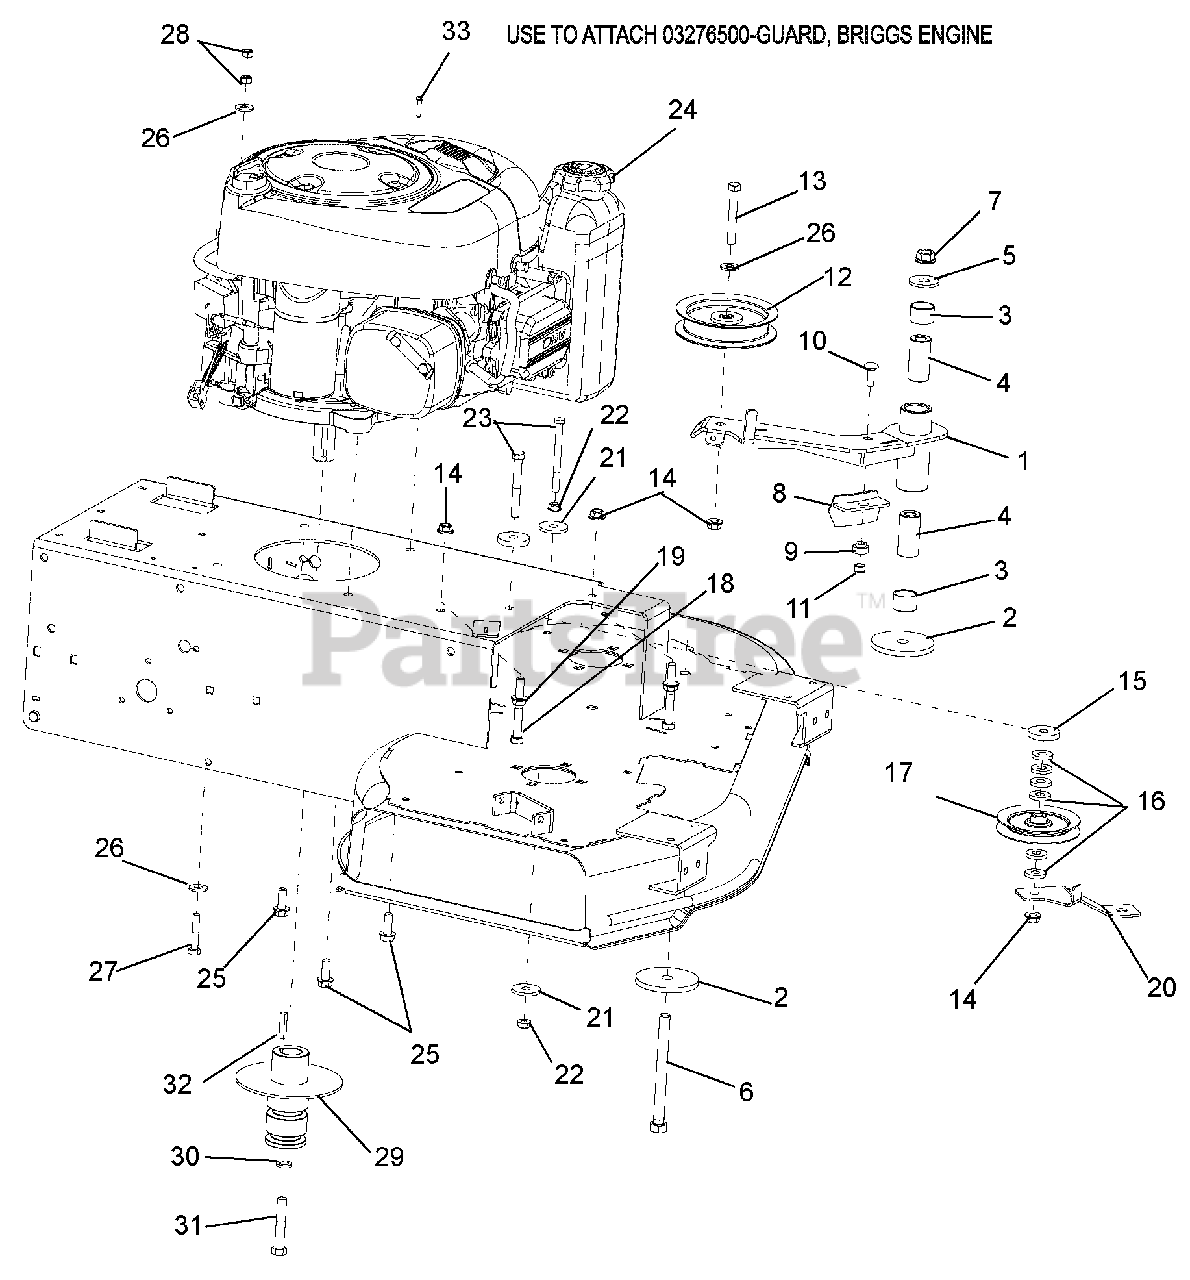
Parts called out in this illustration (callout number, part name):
1	Weldment Arm, PTO Idler
2	Washer, Flat .531 x 3.00 x .25
3	Bearing 1.00 x 1.12 x .75
4	Bushing, Spacer .505/.500 x .999/.996 x 2.05/2.03
5	Washer, Flat Steel .511 x 1.44 x .125
6	Bolt, Hex .50-13 x 5.50
7	Nut, Locking Top Flange .50-13
8	Assembly, Brake Pad
9	Bushing, Flange
10	Bolt, Round Head Square Neck .31-18 x 1.00 Grade 5
11	Nut, Locking Nylon .312-18
12	Idler, Flat .38 x 4.00 x 1.06
13	Bolt, Hex .38-16 x 2.75
14	Nut, Locking Top Flange .38-16
15	Washer, Flat Steel .406 x 1.50 x .245
16	Washer, Flat Steel .43 x 1.00 x .160
17	Idler, 4.00 x .38
18	Bolt, Hex .38-16 x 3.00
19	Nut, Flange .375-16
20	Bracket, Idler Brace
21	Washer, Flat Steel .406 x 1.375 x .135
22	Nut, Spin-Lock Flange .312-18
23	Bolt, Hex .31-18 x 3.50
24	Engine, 10.5 h.p. 49-State (404)
25	Screw, Hex Washer Head Tapping .38-16 x 1.00
26	Washer, Flat Steel .38 x .875 x .083
27	Bolt, Hex .31-18 x 1.75
28	Nut, Locking Center .31-18
29	Pulley, Deck Drive
30	Washer, Locking .44 x .109
31	Bolt, Hex .44-20 x 2.50
32	Key, Square .25 x 1.25 x .25
33	Screw, 8-16 x .87 Pan Head 3-Lobe
